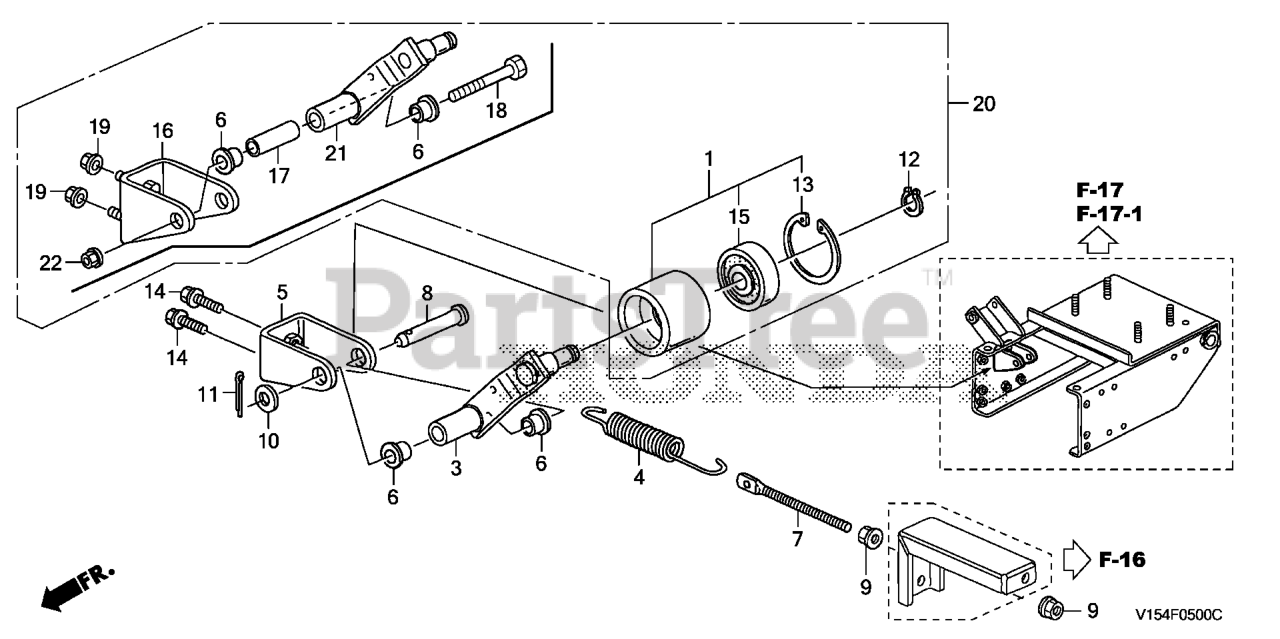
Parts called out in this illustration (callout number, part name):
1	ROLLER, TENSION
4	SPRING, BELT TENSION
6	BUSH, CHANGE ARM
7	BOLT, ADJUSTING (8X80)
9	NUT, FLANGE (8MM)
12	CIRCLIP (OUTER) (20MM)
13	CIRCLIP (INNER) (47MM)
15	BEARING, RADIAL BALL (6204UU)
16	BRACKET, TENSION ARM
17	COLLAR (8.1X12X37.1)
18	BOLT, HEX. (8X55)
19	NUT, FLANGE (8MM)
21	ARM, TENSION
22	NUT, FLANGE (8MM)
